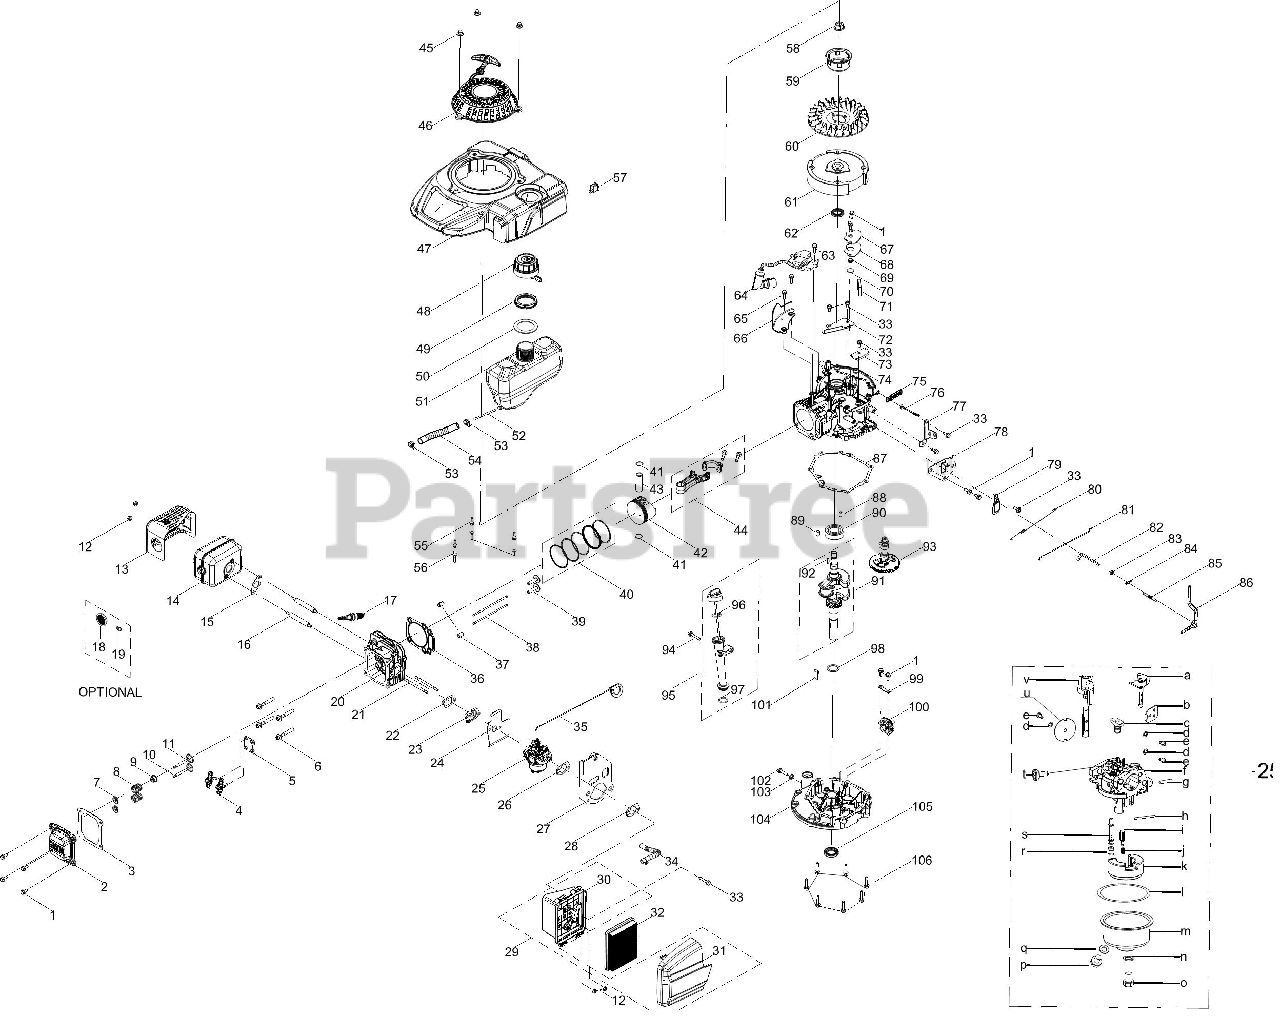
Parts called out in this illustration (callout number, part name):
1	Bolt M6x14
2	Valve Cover
3	Valve Cover Gasket
4	Rocker Arm Assembly
5	Push Rod Guide
6	Bolt M8x54 Cylinder Head
7	Valve Spring Retainer
8	Valve Spring
9	Intake Valve Seal
10	Exhaust Valve
11	Intake Valve
13	Muffler Shield
14	Muffler Assembly
15	Muffler Gasket
16	Muffler Stud M6x95
17	Spark Plug/F5RTC
18	Spark Arrestor
19	Spark Arrestor Screw
20	Cylinder Head
21	Carb Stud M6x87
22	Carburetor Insulator Gasket
23	Carburetor Insulator
24	Carburetor Gasket
25	Carburetor Assembly
26	Air Filter Base Gasket
27	Air Filter Bracket
28	Air Filter Bracket Gasket
29	Air Filter Assembly
30	Air Filter Base
31	Air Filter Cover
32	Air Filter Element, Paper
33	Bolt M6x12
34	Breather Hose Assembly
35	Choke Control
36	Cylinder Head Gasket
37	Cylinder Head Dowel Pin 10x16
38	Push Rod
39	Tappet
40	Piston Ring Set
41	Piston Pin Snap Ring
42	Piston
43	Piston Pin
44	Connecting Rod Assembly
45	Starter Acorn Nut
46	Starter Recoil Assembly
47	Engine Shroud Assembly
48	Fuel Cap Assembly
49	Fuel Tank Upper Grommet
50	Fuel Tank Nut
51	Fuel Tank
52	Fuel Filter
53	Fuel Hose Clamp
54	Fuel Hose
55	Shroud Stud M6x78.5
56	Shroud Stud M6x74
57	Ignition Switch
58	Flywheel Nut M14
59	Starter Cup
60	Cooling Fan
62	Upper Crankshaft Seal
63	Bolt M6x20
64	Ignition Coil Assembly
65	Bolt M6x25
66	Engine Brake Cover Plate
67	Breather Cover Plate
68	Breather Gasket
69	Breather Valve Spring
70	Breather Valve
71	Breather Screen
72	Air Vane Cover Plate
73	Ground Wire Cover Plate
75	Flexible Clamp
76	Grounding Wire
77	Choke Control Bracket
78	Component Bracket
79	Governor Shield
80	Throttle Linkage Spring
81	Throttle Linkage
82	Governor Arm Shaft
83	Governor Seal
84	Governor Arm Shaft Cotter Pin
85	Governor Spring
86	Governor Arm Assembly
87	Crankcase Cover Gasket
88	Crankcase Cover Dowel Pin 7x14
89	Crankcase Cover Dowel Pin 9x14
90	Main Bearing
91	Crankshaft Assembly
92	Flywheel Key
93	Camshaft Assembly
94	Bolt M6x35
95	Dipstick Assembly
96	Dipstick / Oil Fill Tube O-Ring
97	Dipstick / Oil Fill Tube O-Ring
98	Crankshaft Thrust Washer
99	Governor Gear Mounting Plate
100	Governor Gear/Shaft Assembly
101	Oil Return Seal
102	Oil Drain Plug
103	Oil Drain Plug Washer
104	Crankcase Cover
105	Lower Crankshaft Seal
106	Bolt M6x28
